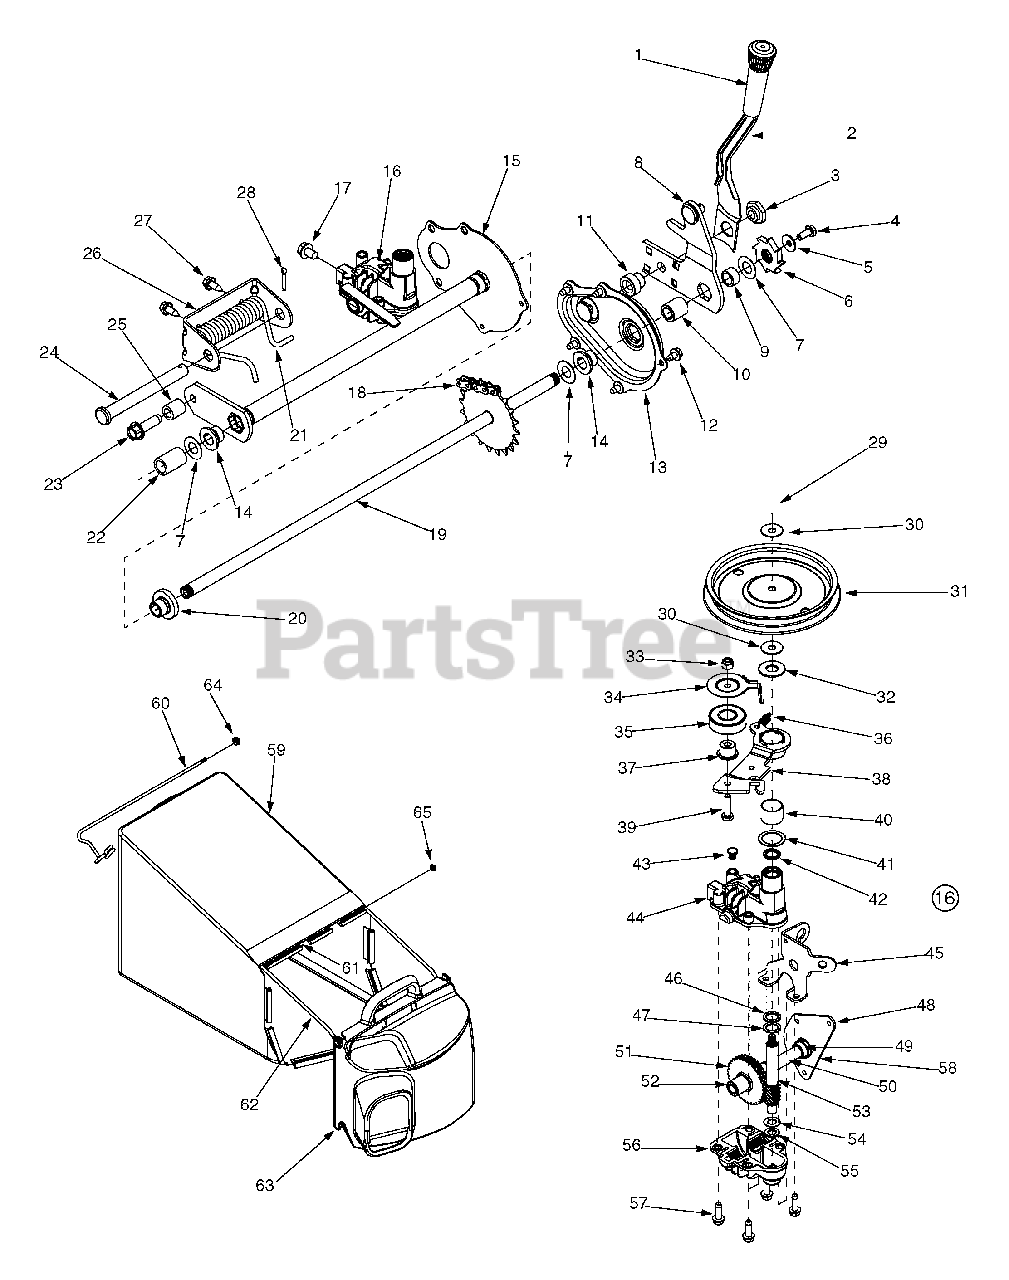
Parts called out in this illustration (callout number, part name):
2	Spring Lever
3	Shoulder Nut .825 x .165 Lg.
4	Cap Screw 1/4-20 x .620
5	Bell Washer .285 ID x .75 OD
6	Wheel Ratchet
7	Flat Washer .508 ID x 1.0 OD
9	Spacer .510 ID x .70 OD
10	Sleeve Bearing .504 ID x .830 OD
11	Shoulder
12	Tap Screw 1/4-20 x .375
16	Transmission Assembly Complete
17	Hex Screw 5/16-18
18	Chain
19	Rear Axle Assembly
20	Flange Bearing .506 ID x .715 Lg
21	Torsion Spring
22	Spacer .550 ID x .750 OD
23	Screw 3/8-16 x .25
24	Clevis Pin .50 Dia x 4.82 Lg.
25	Spacer .385 ID x .624 OD
28	Cotter Pin
29	Hex Jam Nut 5/16-24
30	Bell Washer .325 ID x .930 OD
31	Pulley
32	Flat Washer .510 ID x 1.120 OD
33	Hex Jam Nut 1/4-28
34	Belt Keeper
35	Bearing
36	Extension Spring
37	Flange Spacer
38	Idler Bracket Assembly
39	Hex Cap Screw 1/4-28 x 1.0
40	Bearing Sleeve
41	Flat Washer .885 ID x 1.45 OD
42	Oil Seal
44	Upper Housing Assembly
47	Thrust Washer .504 ID x .70 OD
48	Pivot Bracket
49	Flange Bearing
50	Output Shaft 6T
51	Gear 34T
52	Bearing
53	Pinion Shaft 10T
54	Thrust Washer 3/8 x .70
55	Thrust Washer .388 x .625
56	Lower Housing Assembly
57	Hex Screw 1/2-20 x .75
58	Shaft Assembly
59	Grassbag
61	Pivot Rod
63	Grassbag Cover
64	Hex Nut 5/16-18
65	Cap Nut
